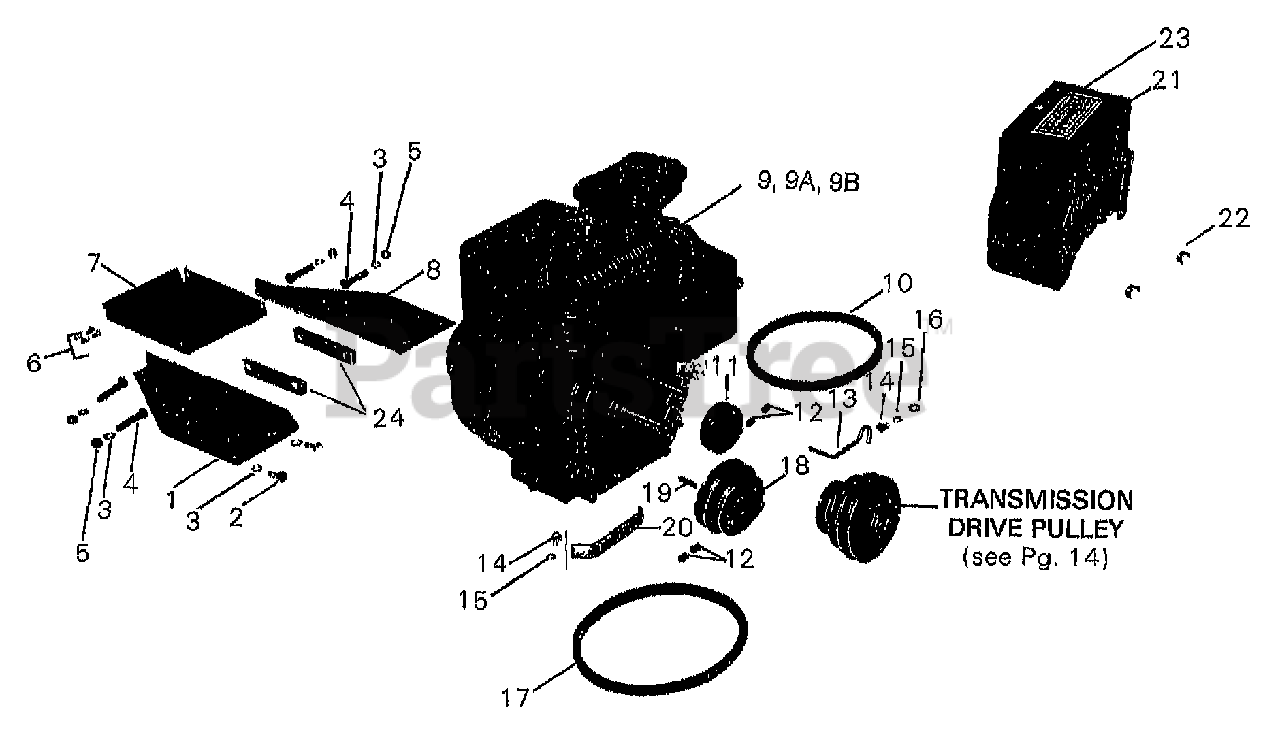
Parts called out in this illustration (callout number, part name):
1	BRKT-ENG MTG LT
2	SCR-HHC 5/16-18X.75 GR 5 ZP
3	WASHER-LK .312 ZP
4	SCR-HH 5/16-18X1.5 G5 ZP
5	NUT-HEX 5/16-18 ZP
6	SCR-HH SEMS 10-32 X .5 (SEMS W/PERMANENT WASHER)
7	PAN-ENG BRKT PNT
8	BRKT-ENG MTG RT
9	ENGINE, BRIGGS & STRATTON, STD. RECOIL START, 4HP, MODEL 100292, TYPE 0536-01
9A	ENGINE, BRIGGS & STRATTON, STD. RECOIL START, 5HP, MODEL 130292, TYPE 0793-01
9B	ENGINE, BRIGGS & STRATTON, ELEC. START, 5HP, MODEL 130297, TYPE 0782-01
10	BELT-V - REVERSE (SEE V-BELT SET)
11	PULLEY-ENG MACH
12	SCR-SS 5/16-18X.375
13	GUIDE-BELT FWD
14	SCR-HH 1/4-20X.75 G5 ZP
15	WASHER-LK .25 ZP
16	WASHER-FLAT 1/4 SAE
17	BELT-V - FORWARD (SEE V-BELT SET)
18	KIT-ENG PULLEY PONY
19	KEY-.188 SQX1.0
20	GUIDE-BELT REV
21	WELD-BELT SHROUD
22	NUT-WING/LK 1/4-20 ZP
23	DECAL-BELT POSITION
24	SHIM-4.38X.88X.134 (NON-CURRENT PART - CONTACT FACTORY)
